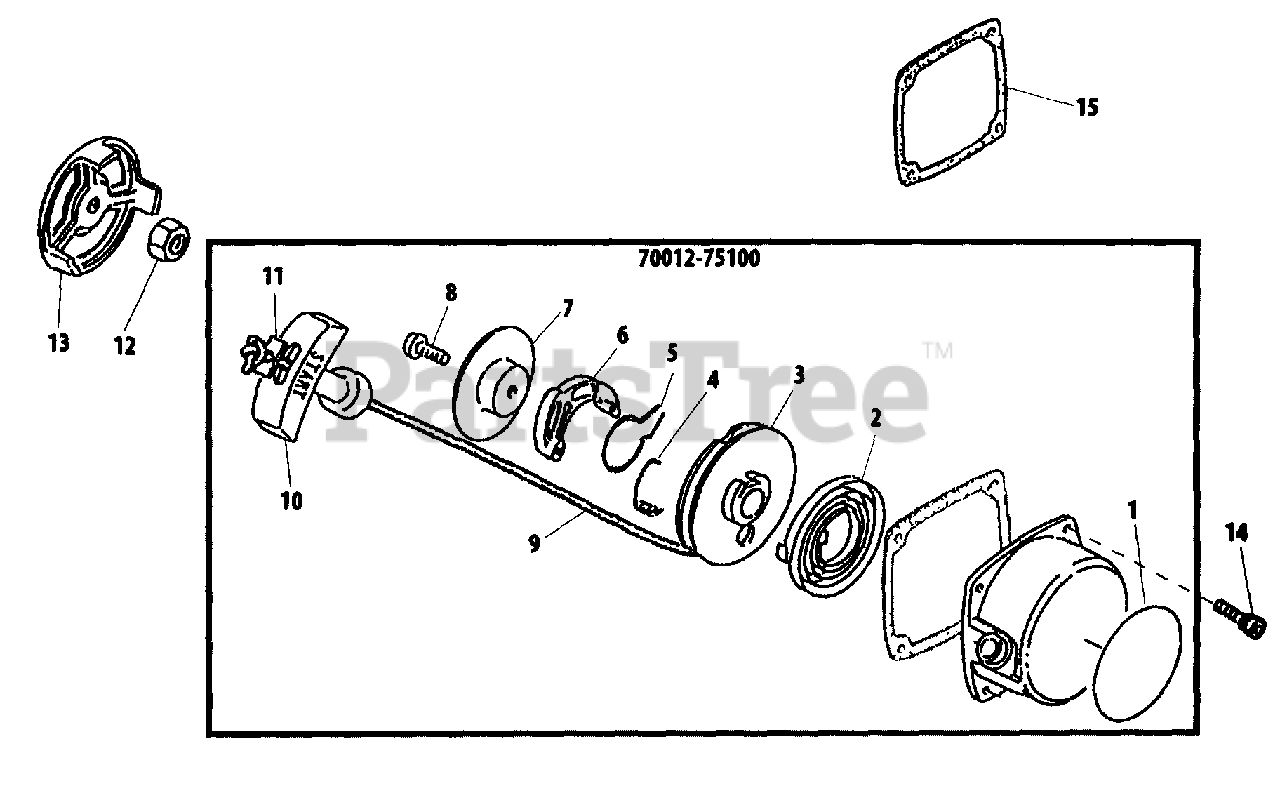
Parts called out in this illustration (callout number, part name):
1	LABEL
2	SPRING, REWIND
3	REEL, ROPE
4	SPRING, RETURN
5	SPRING
6	PAWL, STARTER
7	PLATE, STARTER
8	SCREW
9	ROPE
10	GRIP, STARTER
11	RETAINER, ROPE
12	NUT - 8
13	CATCHER, STARTER
14	SCREW - 4X16
15	GASKET
70012-75100	STARTER ASSY
